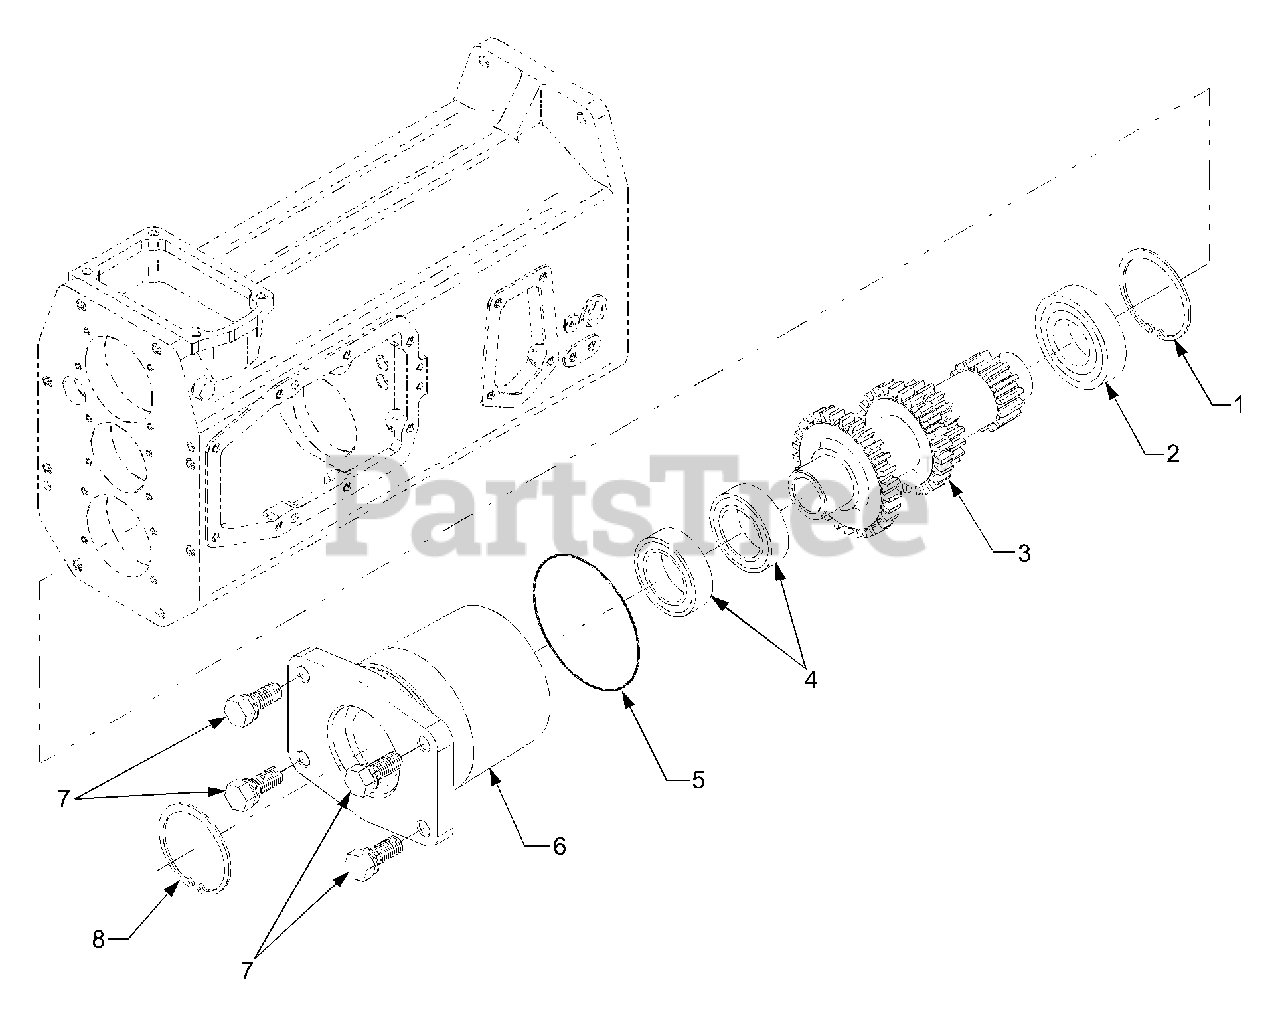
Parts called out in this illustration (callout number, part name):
2	Bearing, Ball
3	Gear, 29-23-18-14
4	Bearing, Ball
6	Case, Bearing
